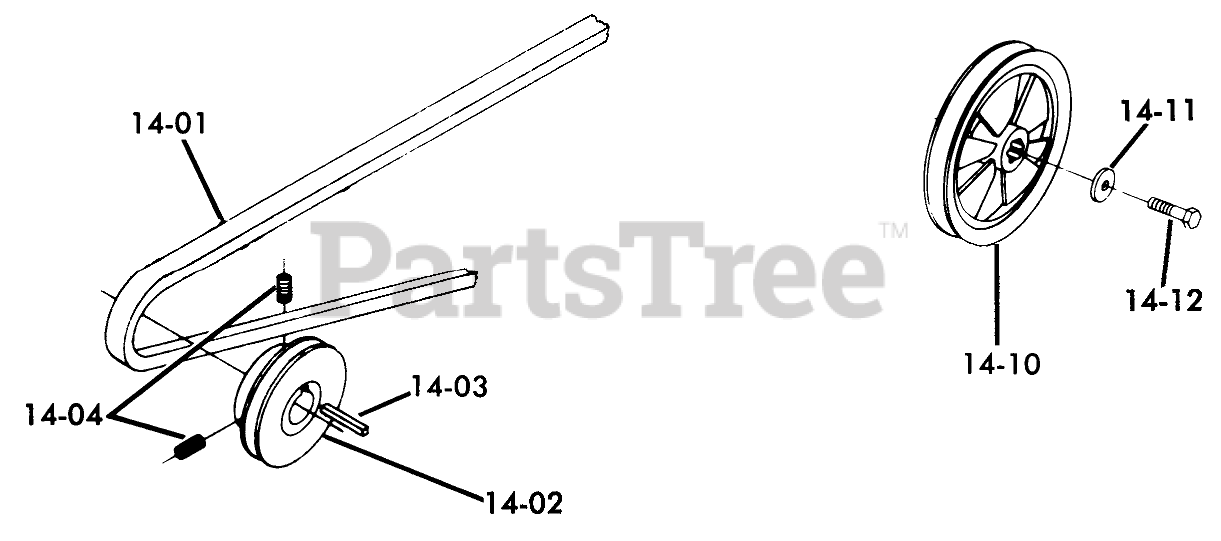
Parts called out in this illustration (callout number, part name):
14-01	V BELT
14-02	PULLEY
14-04	Set Screw
14-10	PULLEY
14-11	WASHER
14-12	Bolt
